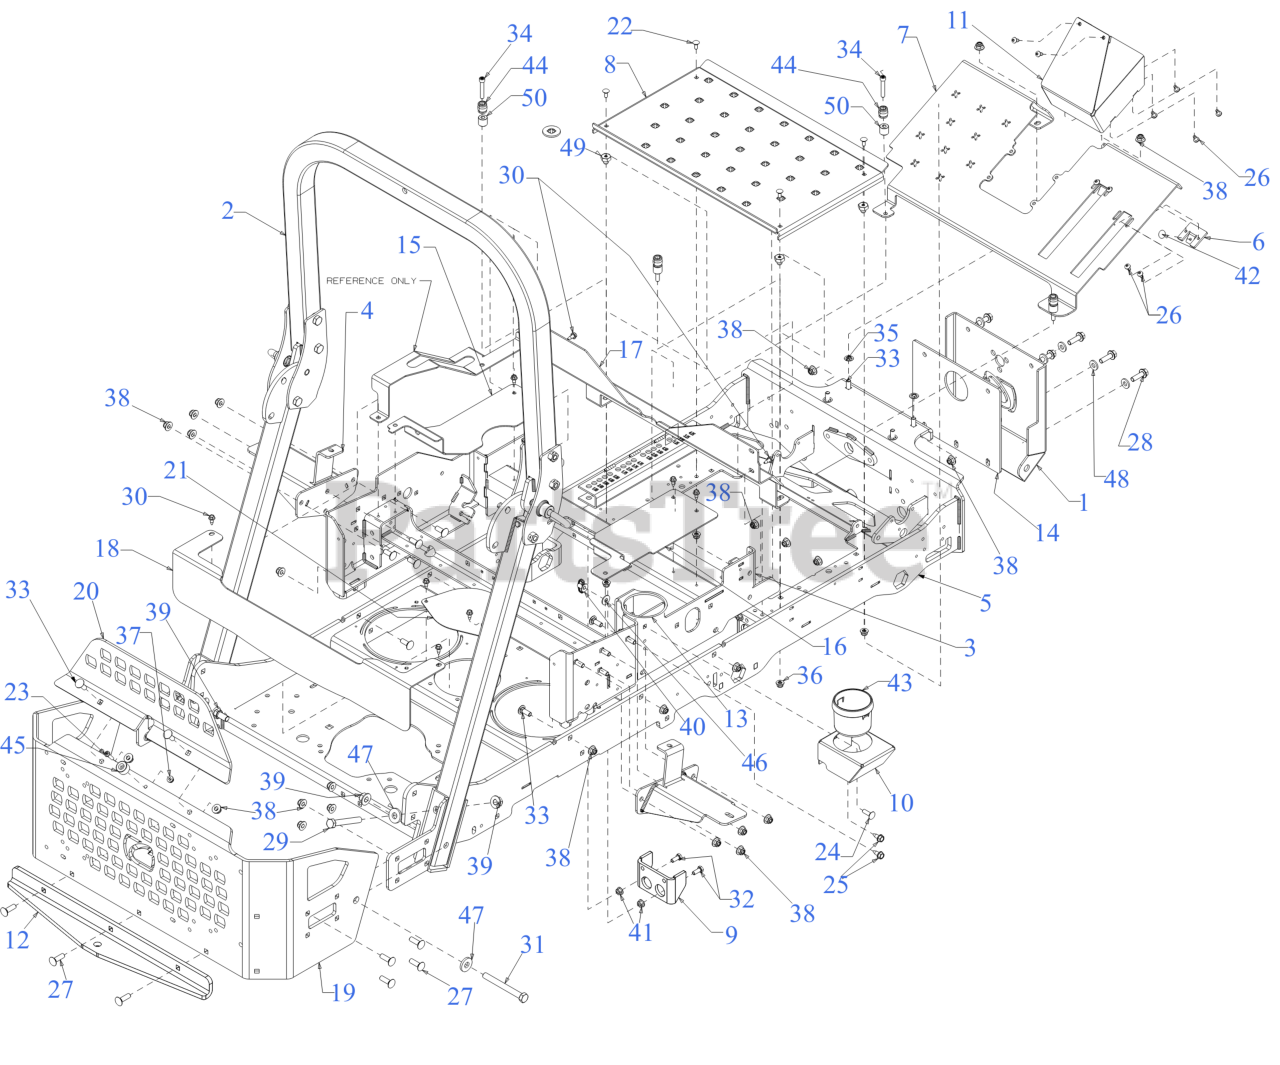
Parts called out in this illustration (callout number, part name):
2	PRO Z ROPS KIT
3	SEAT FRAME
4	FUEL TANK MOUNT
5	FRAME
6	REVERSE PEDAL STOP BRACKET
9	FRONT DECK LIFT MOUNTING BRACKET
10	LOWER CUP HOLDER
14	FRONT MOUNTING PLATE SPACER
15	SEAT COVER PANEL (LH)
16	SEAT COVER PANEL (RH)
17	SEAT BOX COVER (FRONT)
18	SEAT BOX COVER (REAR)
19	BUMPER (LOWER RR)
20	BUMPER (UPPER RR)
21	FRAME COVER PLATE
22	CARRIAGE BOLT 1/4-20 x .62
23	MACHINE SCREW 1/4-20:1
24	CARRIAGE BOLT 5/16-18 x 1.00
25	SCREW 5/16-18 x .750
26	SCREW 1/4-20 x .5
27	CARRIAGE BOLT 3/8-16 X1.25 GR5
28	SCREW 3/8-16 x 1.25 GR5
29	HEX SCREW 1/2-13 x 3.50
30	SCREW 1/4-20X.625
31	SCREW 1/2-13 x 4.5 GR 5
32	SCREW 5/16-18 x .75 GR5
33	CARRIAGE BOLT 3/8-16 x 1.00 GR5
34	SCREW 5/16-18X1.75 GR5
36	FLANGE LOCK NUT 5/16-18
37	FLANGE LOCK NUT
40	WING NUT 5/16-18
41	HEX FLANGE NUT
42	RATCHET CLIP
44	RADIAL BUMPER
46	FLAT WASHER
47	FLAT WASHER .531 x 1.25 x .181
48	FLAT WASHER
49	SHOULDER SPACER
